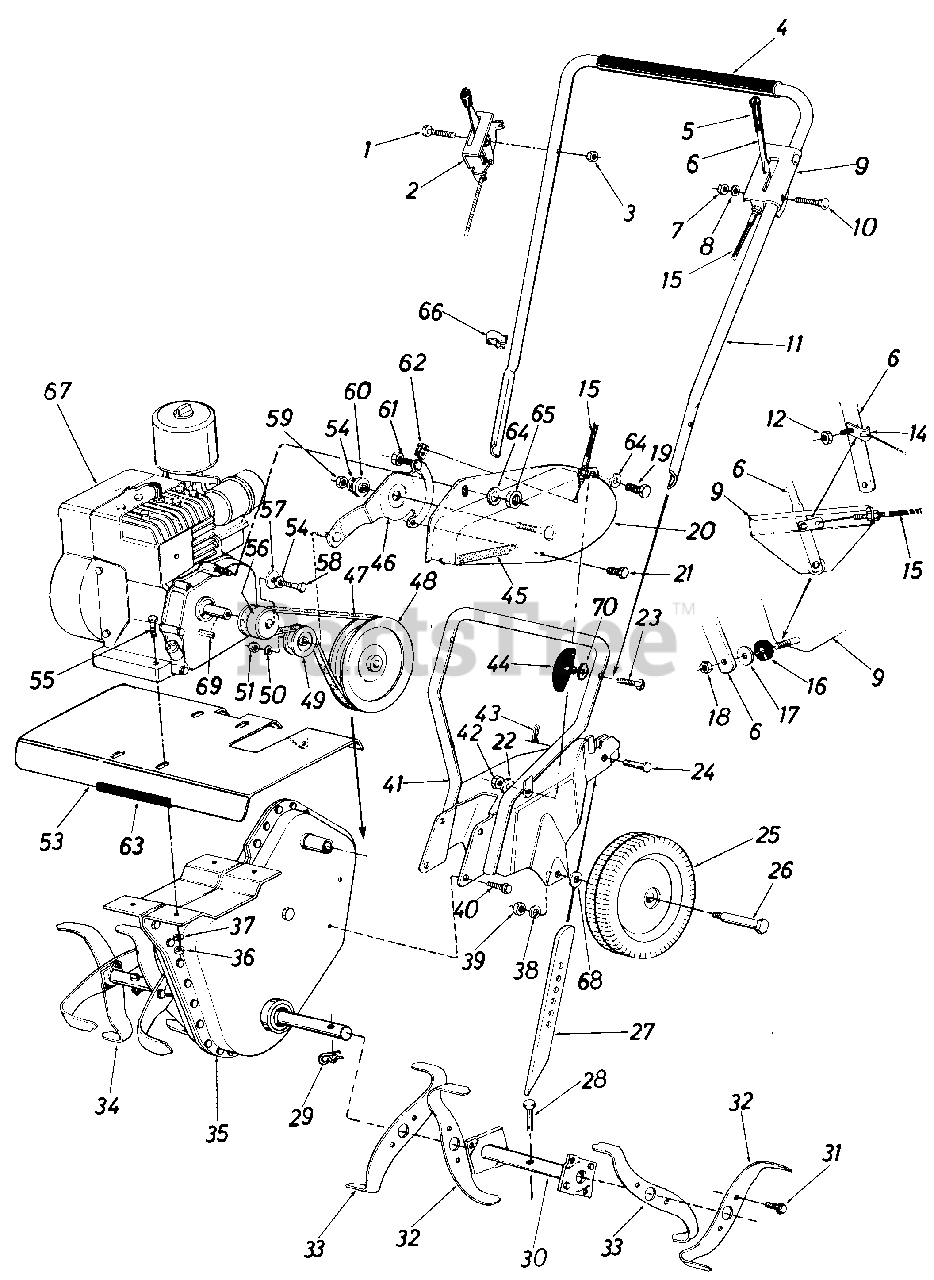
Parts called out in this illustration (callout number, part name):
1	Hex Bolt 1/4-20 x 1.50" Lg.
2	Throttle Control Ass'y. Comp.
3	Hex Cent. L-Nut 1/4-20 Thd.
4	Grip 14" Lg.
5	Handle Grip
6	Clutch Handle Ass'y.
7	Hex Cent. L-Nut 1/4-20 Thd.
8	Fl-Wash. 1/4" I.D. x .50" O.D. x .063
9	Clutch Handle Brkt. Ass'y.
10	Carr. Bolt 1/4-20 x 1.25" Lg.
11	Upper Handle
12	Hex Cent. L-Nut 1/4-20 Thd.
14	Clevis
15	Clutch Cable
16	Rubber Wash.
17	Fl-Wash. 1/4" I.D. x .75" O.D. x .063
18	Hex Cent. L-Nut 1/4-20 Thd.
19	Hex Bolt 1/4-20 x .75" Lg.
20	Belt Cover Ass'y.
21	Hex Wash. Hd. Tap Scr. 1/4 x .50
22	L-Wash. 1/4" I.D.
23	Curved Hd. Bolt 5/16-18 x 1.75" Lg.
24	Clevis Pin
25	Wheel Ass'y. 7"
26	Shoulder Bolt
29	Hairpin Cotter
36	Hex Nut 5/16-18 Thd.
37	L-Wash. 5/16" I.D.
38	L-Wash. 3/8" Scr. H.D.
39	Hex Cent. L-Nut 3/8-16 Thd.
40	Hex Wash. SF-Tap Scr. 5/16-18 x 50" Lg.
43	Intern. Cotter Pin
44	Hand Knob
45	Extension Spring 4.88" Lg.
46	Idler Arm Ass'y.
47	Belt 3/8" x 29" Lg.
48	Chain Case Pulley 5-1/2 x 1/2"
49	Fl-Idler 2"
50	L-Wash. 5/16" I.D.
51	Hex Nut 3/8-24 Thd.
55	Hex Bolt 5/16-18 x 1.5" Lg.
56	Engine Pulley 3/8 V x .7525 I.D. x 2" O.D.
57	Fl-Wash. .385 I.D. x 1.00" O.D. x .135
58	Hex Bolt 3/8-24 x 1.00" Lg.
59	Hex Nut 5/16-18 Thd.
60	Shld. Spacer .50" Dia. x .133
61	Hex Cent. L-Nut 1/4-20 Thd.
62	Clevis
63	Trim Strip 4"
64	L-Wash. 1/4" I.D.
65	Hex Cent. L-Nut 1/4-20 Thd.
66	Cable Tie
67	Engine
68	Bell-Wash.
69	Square Key 3/16 x 314" Lg.
70	Belleville Washer
